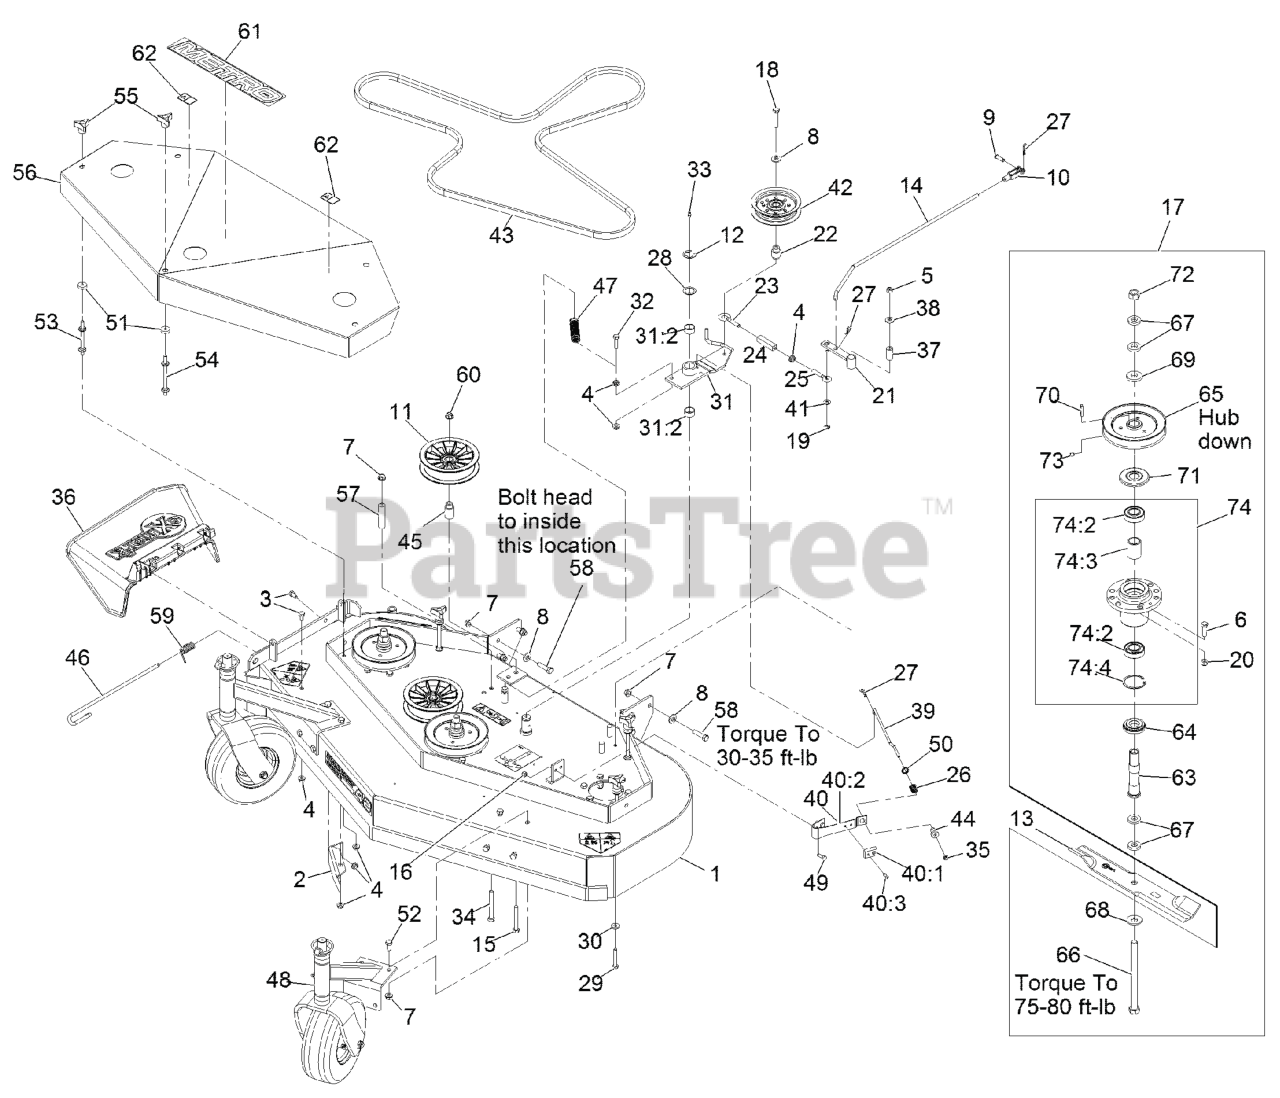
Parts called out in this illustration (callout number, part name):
1	DECK-SERVICE, 48
2	BAFFLE-DOGLEG
3	SCREW-HH
5	NUT-LOCK, NI
6	SCREW-HH
7	NUT-HHF, WHIZ
8	WASHER-BELLEVILLE
9	PIN-CLEVIS
10	YOKE-ADJUSTABLE
11	PULLEY,IDLER 5"
12	RING-RETAINING, EXT
14	ARM-ASSIST, LINKAGE
15	SCREW-HH
16	NUT-LOCK, NI
17	ASM, CUTTER HOUSING OUTER
18	SCREW-HH
19	RING-RETAINING, EXT
20	NUT-LOCK, NI
21	ARM-ASSIST, 32/36
22	BUSHING-ENGAGEMENT
23	EYEBOLT-THREAD, LH
24	BODY-TURNBUCKLE
25	EYEBOLT-THREAD, RH
26	SPRING-COMPRESSION
27	PIN-COTTER
28	WASHER-SPINDLE
29	SCREW-HH
30	WASHER-SPRING
31	IDLER ARM ASM
31:2	SLEEVE-BEARING
32	SCREW-HH, SPECIAL
33	FITTING-GREASE
34	SCREW-HH
35	NUT-LOCK, NI
36	CHUTE DEFLECTOR XRK M056
37	TUBE-PIVOT
38	WASHER-FLAT
39	ROD-BRAKE
40	PAD AND SPRING ASM
41	WASHER-PLAIN
43	BELT,BLADE 48
44	SPACER-FLANGED
45	BUSHING-IDLER
46	PIN-CHUTE
47	SPRING-EXTENSION
48	ASM-CASTER MNT W/WEIGHT
49	SCREW-HH
50	RING-PUSH ON
52	SCREW-HH
53	STUD-SHIELD, BELT (SHORT)
54	STUD-SHIELD, BELT (LONG)
55	KNOB-3 PRONG
56	ASM,SHIELD W/DECALS 48 ME
58	SCREW-HH
59	SPRING, TORSION
60	NUT-HF, NI
61	Decal-Metro
62	DECAL-WARNING
63	TUBE-SPINDLE, SHORT
64	SPACER-GUARD, BOTTOM
65	SHEAVE
66	SCREW-CAP, HH
68	WASHER-SPRING
69	WASHER-RETAINER, SHEAVE
71	GUARD-BEARING, TOP
72	NUT-HEX
73	SETSCREW
74	Cutter Housing ASM
74	KIT, CUTTER HOUSING
74:2	BEARING-JACKSHAFT
74:3	SPACER-BEARING
74:4	RING-SNAP
